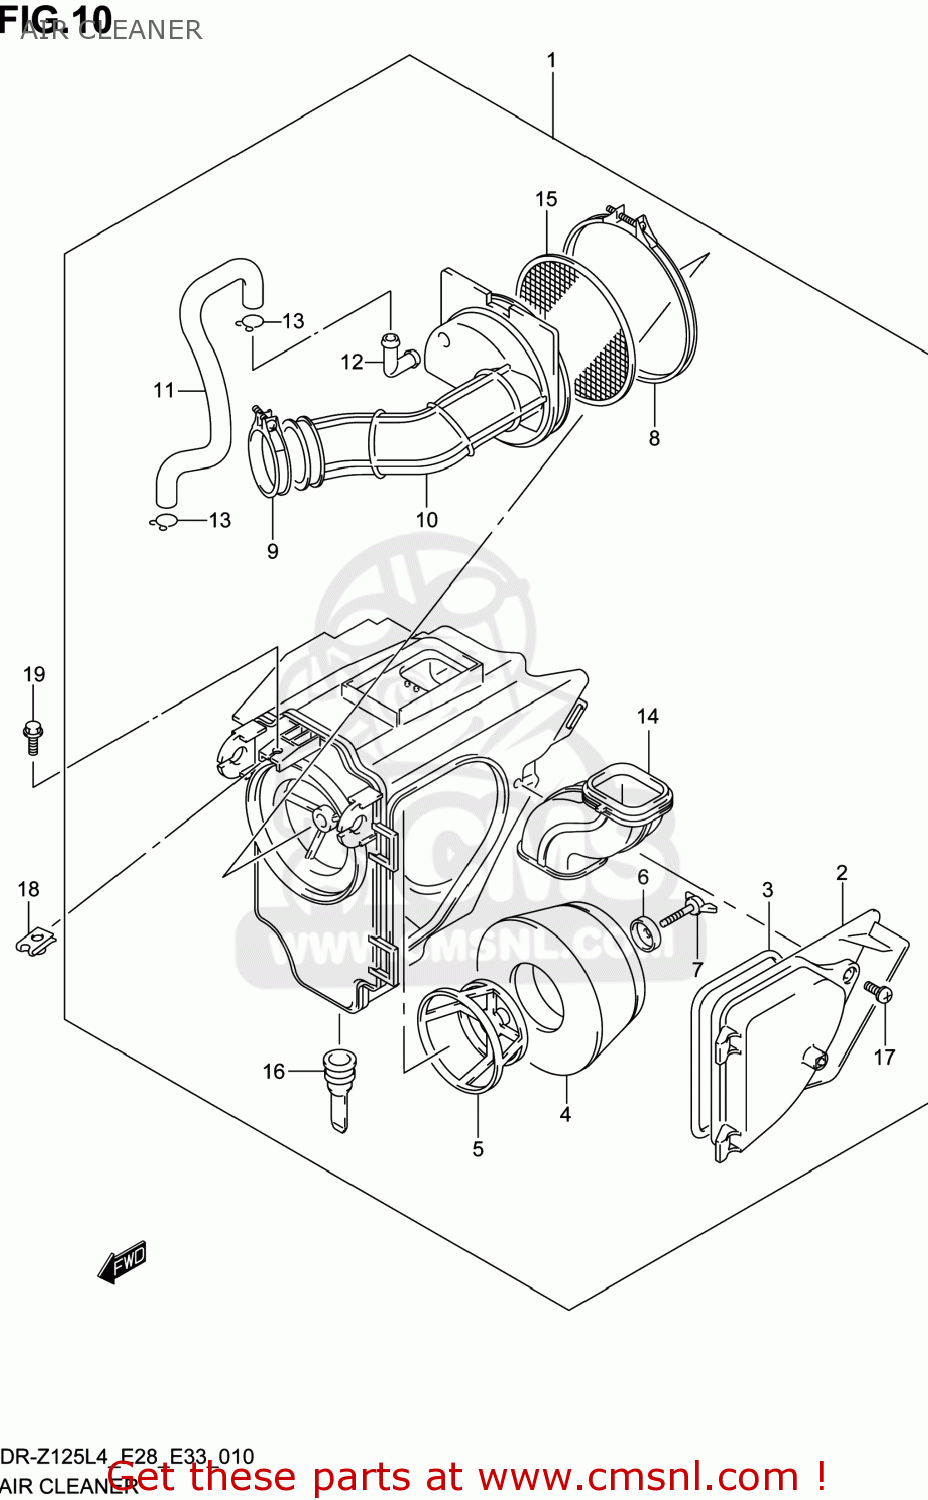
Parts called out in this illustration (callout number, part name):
1	CLEANER ASSY,AIR
2	CAP,AIR CLEANER
3	GASKET (NAS)
4	FILTER
5	HOLDER,FILTER
6	WASHER,AIR CLEANER
7	BOLT,WING
8	CLAMP,OUTLET TUBE
9	CLAMP
10	TUBE,OUTLET
11	TUBE,BREATHER
12	JOINT
13	CLIP
14	TUBE,INLET
15	TRAP,FLAME
16	CAP,DRAIN
17	SCREW
18	NUT
19	BOLT
